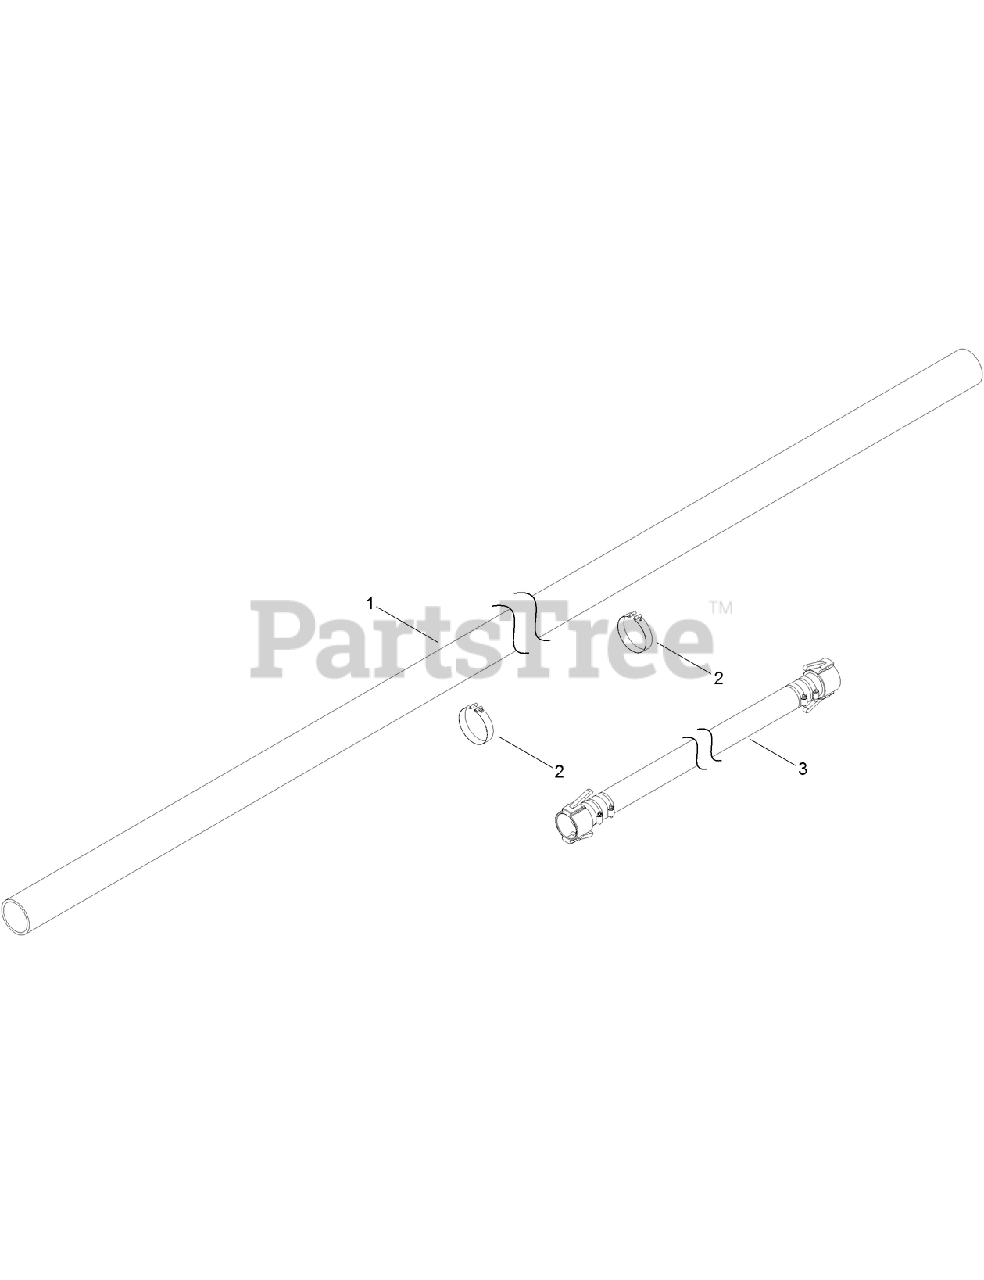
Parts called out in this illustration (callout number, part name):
1	HOSE-SUCTION, WATER
2	CLAMP-T BOLT
3	DISCHARGE HOSE ASM
